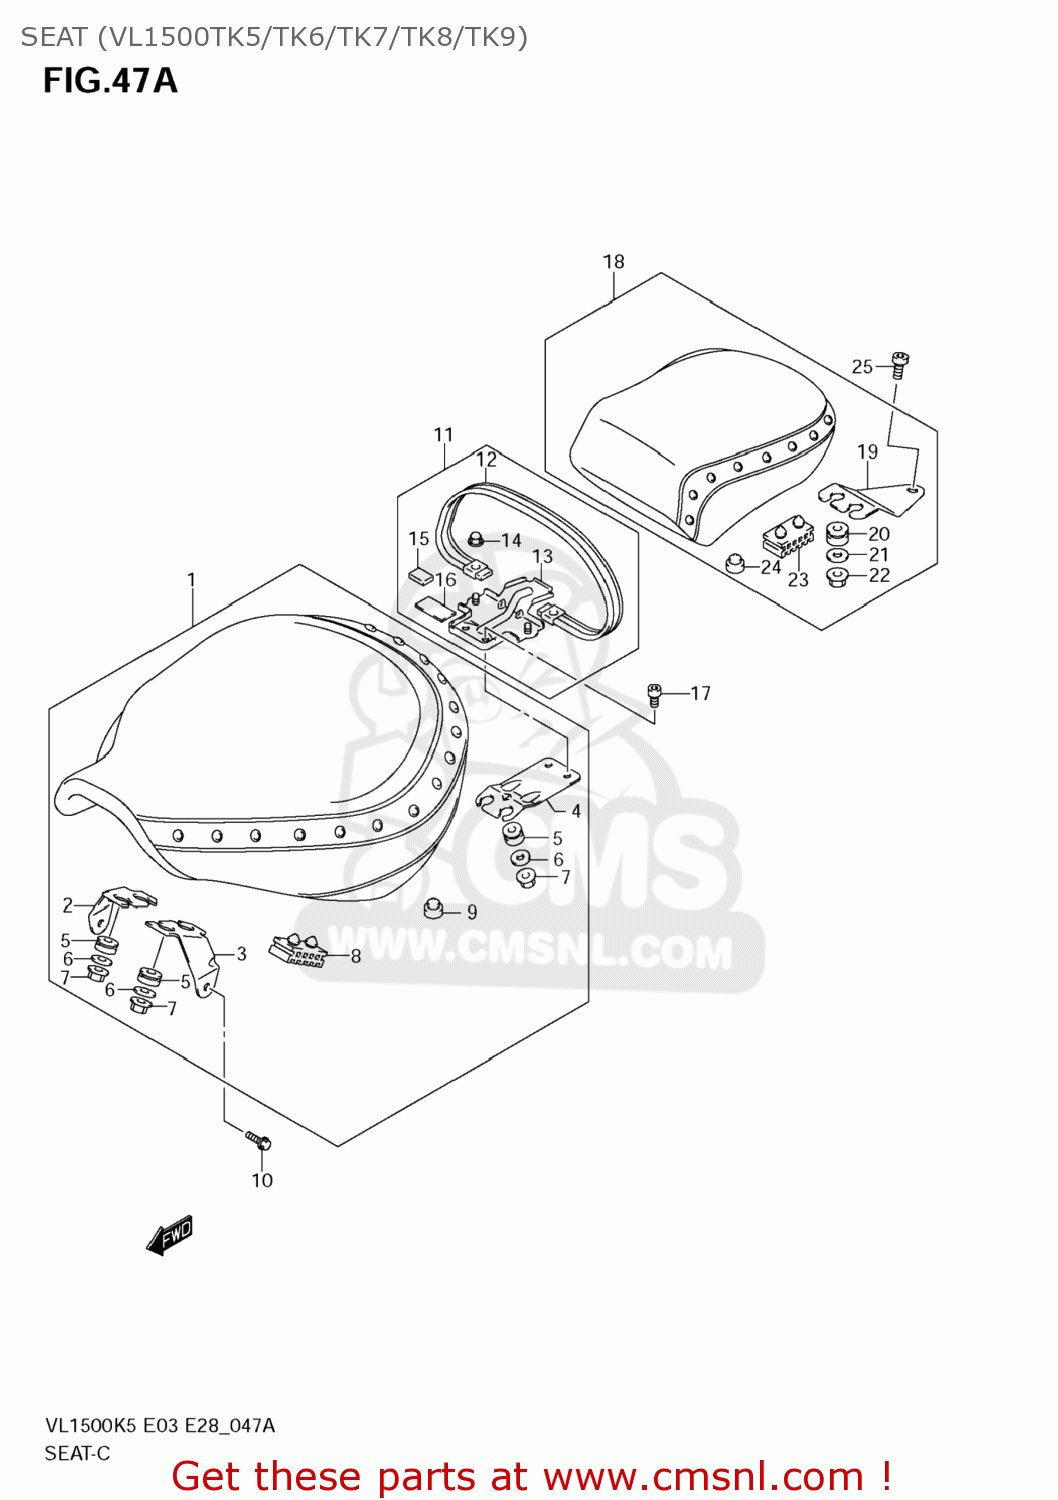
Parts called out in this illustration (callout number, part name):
1	SEAT ASSY
2	BRACKET,FR,R
3	BRACKET,FR,L
4	BRACKET,RR
5	CUSHION
6	WASHER(6.5X20X1.6)
7	NUT
8	CUSHION
9	CUSHION
10	BOLT(8X20)
11	BAND ASSY,SEAT
12	BAND,SEAT
13	BRACKET,SEAT BAND
14	NUT
15	PAD
16	CUSHION
17	BOLT(6X18)
18	SEAT ASSY,PILLION
19	BRACKET,RR
20	CUSHION
21	WASHER(6.5X20X1.6)
22	NUT
23	CUSHION
24	CUSHION
25	BOLT(8X16)
